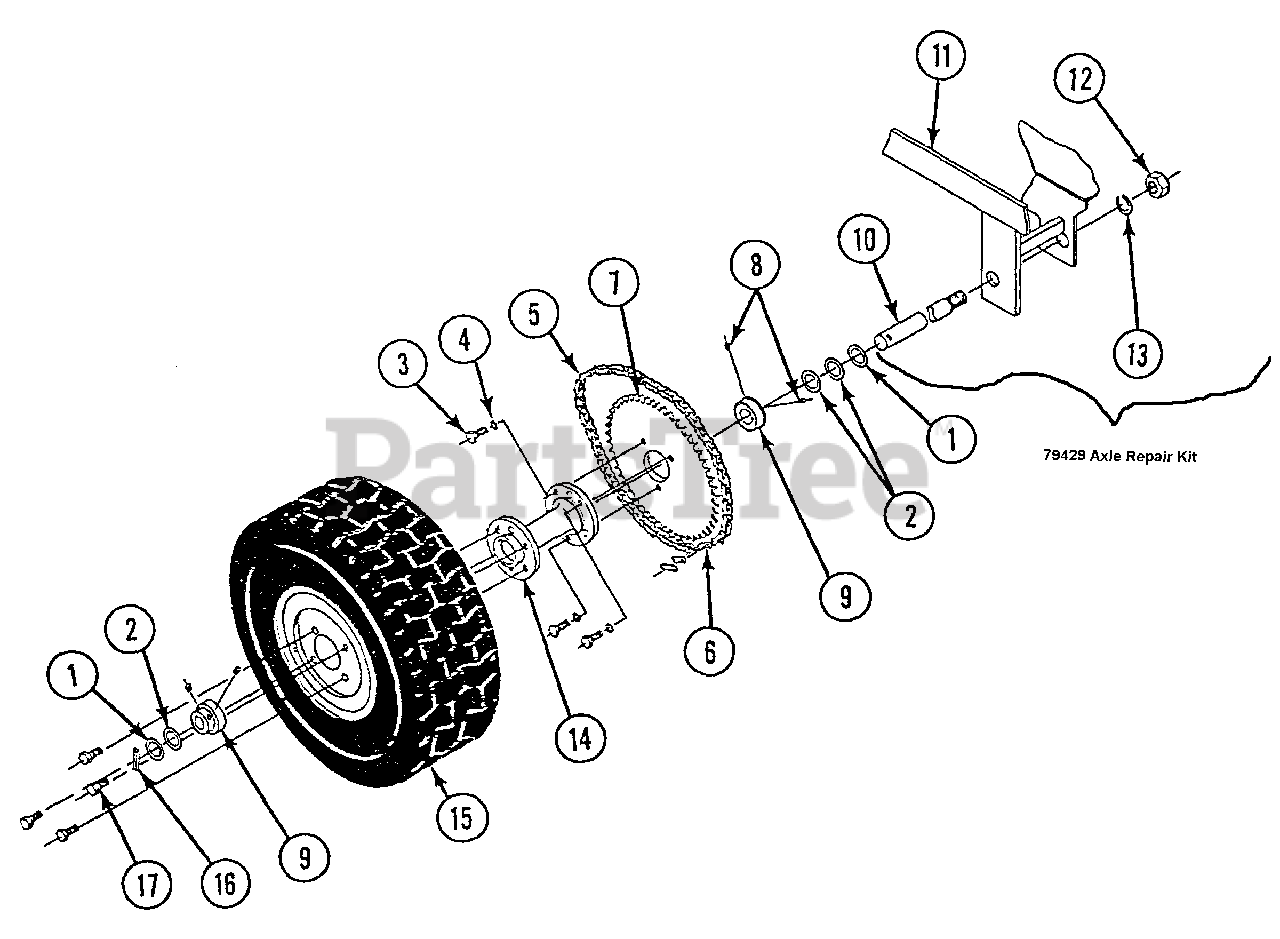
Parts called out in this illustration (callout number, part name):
1	WASHER, 1" SPECIAL
2	WASHER, 1" X 10 GA.
3	CAPSCREW, 1/2-20 X 1 HHCS GR.5
4	LOCKWASHER, 1/2 SPLIT SPRING
5	CHAIN #50, 56 ROLLERS
6	MASTER LINK #50 CHAIN
7	SPROCKET
8	SETSCREW, 1/4-28 X 5/16 W/NYLOC
9	BEARING, 1" BORE
10	AXLE, REMOVEABLE
12	NUT, 7/8-14
13	LOCKWASHER, 7/8 SPLIT SPRING
14	HUB, DRIVE WHEEL
15	TIRE
16	PIN SPIROL, 5/16 X 1-1/2 STD. DUTY
17	LUG BOLT, 1/2-20
79429	AXLE REPAIR KIT
